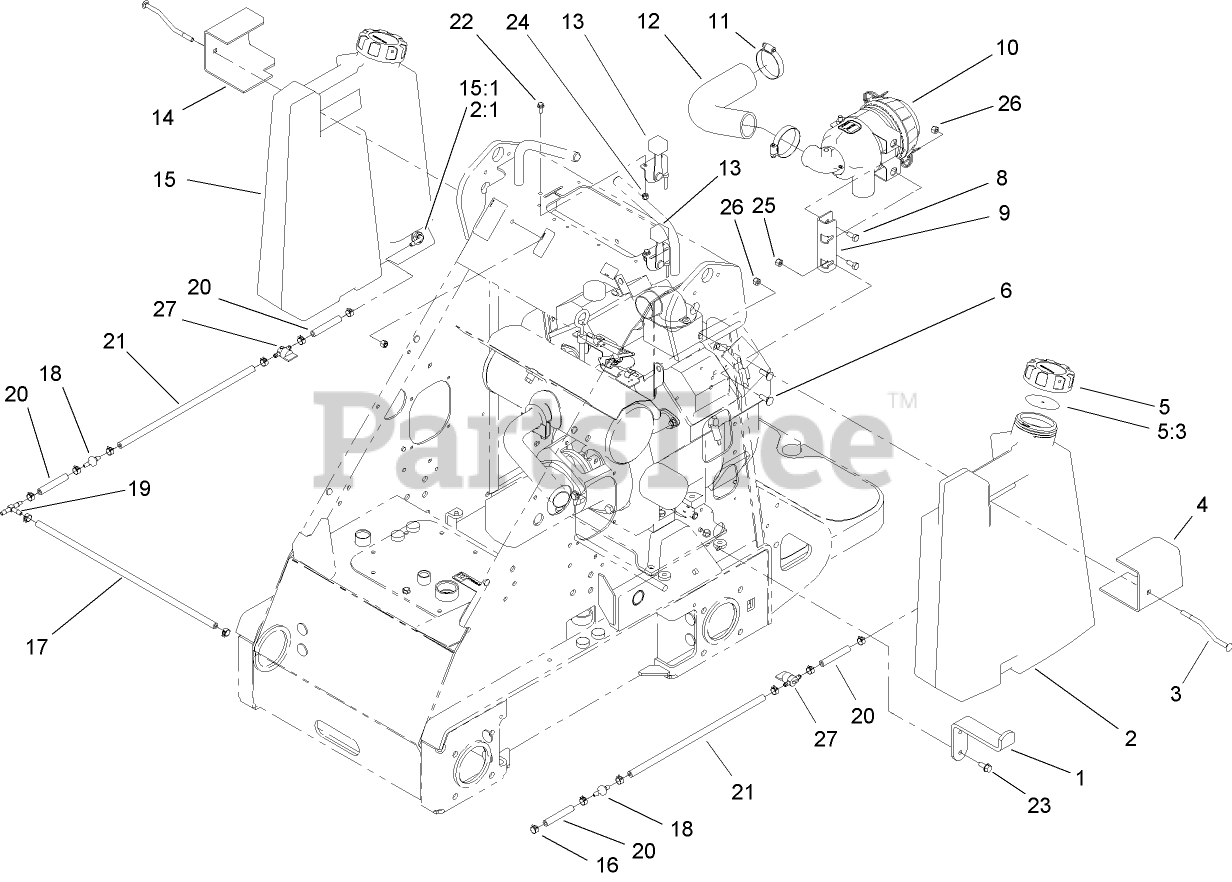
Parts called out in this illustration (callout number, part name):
1	MOUNT-BOTTOM, TANK
2	LH Fuel Tank ASM
2:1	FITTING-FUEL, BULKHEAD
3	BOLT-MOUNT
4	PLATE-MOUNT, LEFT
5	CAP-FUEL, GAS
5:3	GASKET-VENTED
6	BOLT-CARR
8	SCREW-HH
9	MOUNT-CLEANER, AIR
10	AIR CLEANER ASM
11	CLAMP-HOSE
12	HOSE-AIR
13	CONTROL-CHOKE / THROTTLE
14	PLATE-MOUNT
15	RH Fuel Tank ASM
15:1	FITTING-FUEL, BULKHEAD
16	CLAMP-HOSE
17	HOSE-FUEL
18	VALVE-CHECK, FUEL
19	FITTING-TEE, BARBED
20	HOSE-FUEL
21	HOSE-FUEL
22	SCREW-HHF
23	SCREW-HWHTF
24	NUT-LOCK, NI
25	NUT-HF
26	NUT-LOCK, NI
27	VALVE-FUEL
